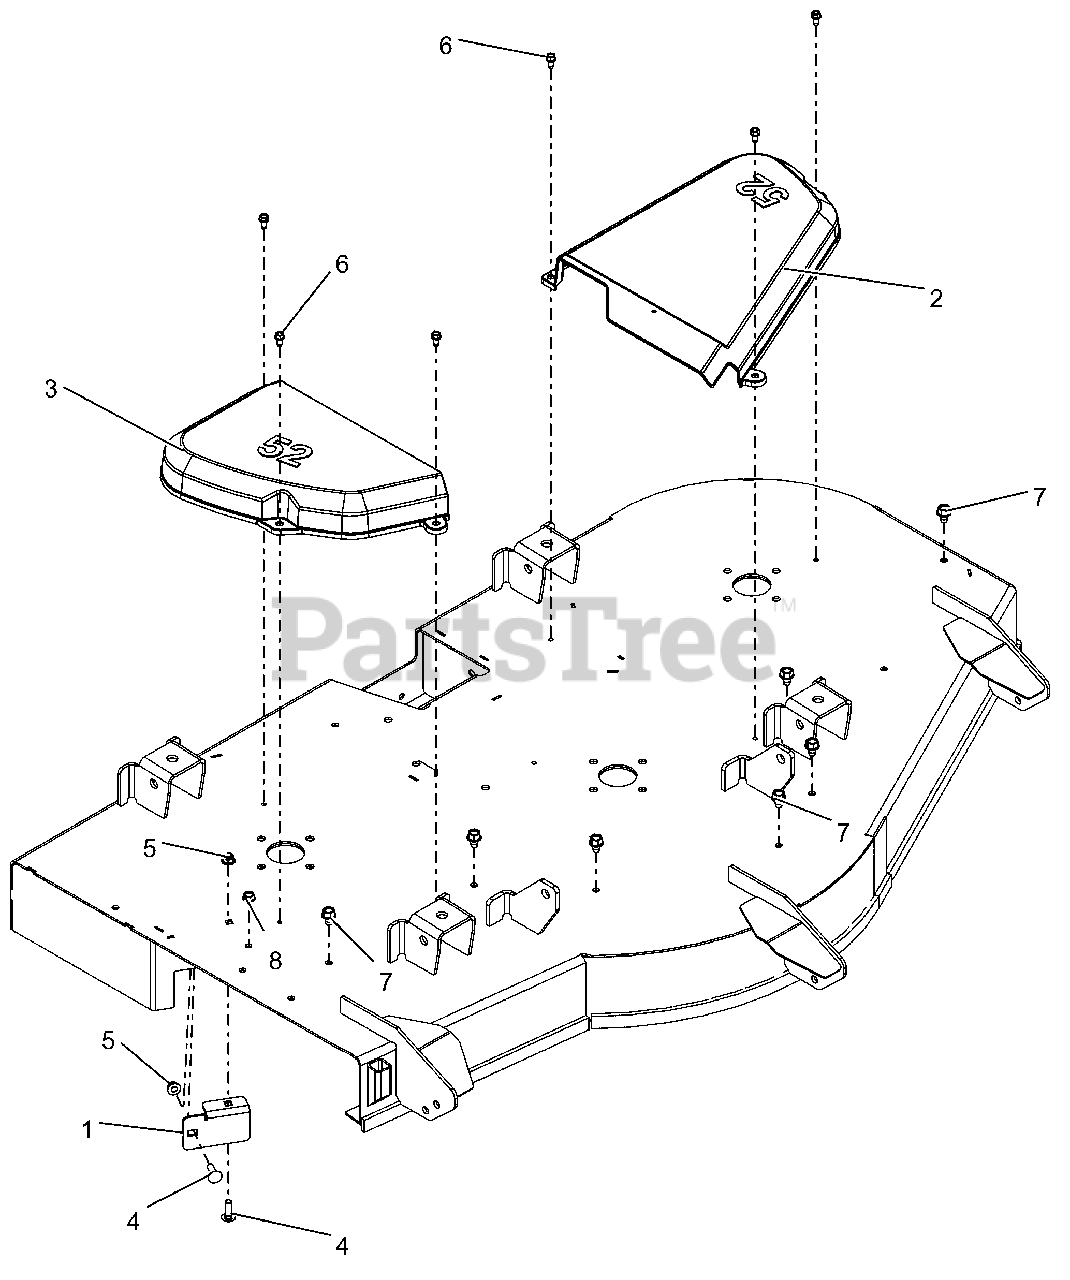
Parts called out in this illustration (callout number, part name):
1	STRIP, DEFLECTOR - 52"
2	COVER, BELT 52" LH
3	COVER, BELT 52" RIGHT
4	BLT,RHSN .31-18X1.00 G5 ZCC
5	NUT,NYL-FLG .31-18 GF ZCC
6	SCR-TAP .25-20X.50 HWH ZCC
7	SCR,TAP .375-16X.50 HWH TR ZCC
8	SCR,TAP .312-18X.50 HWH TR ZCC
